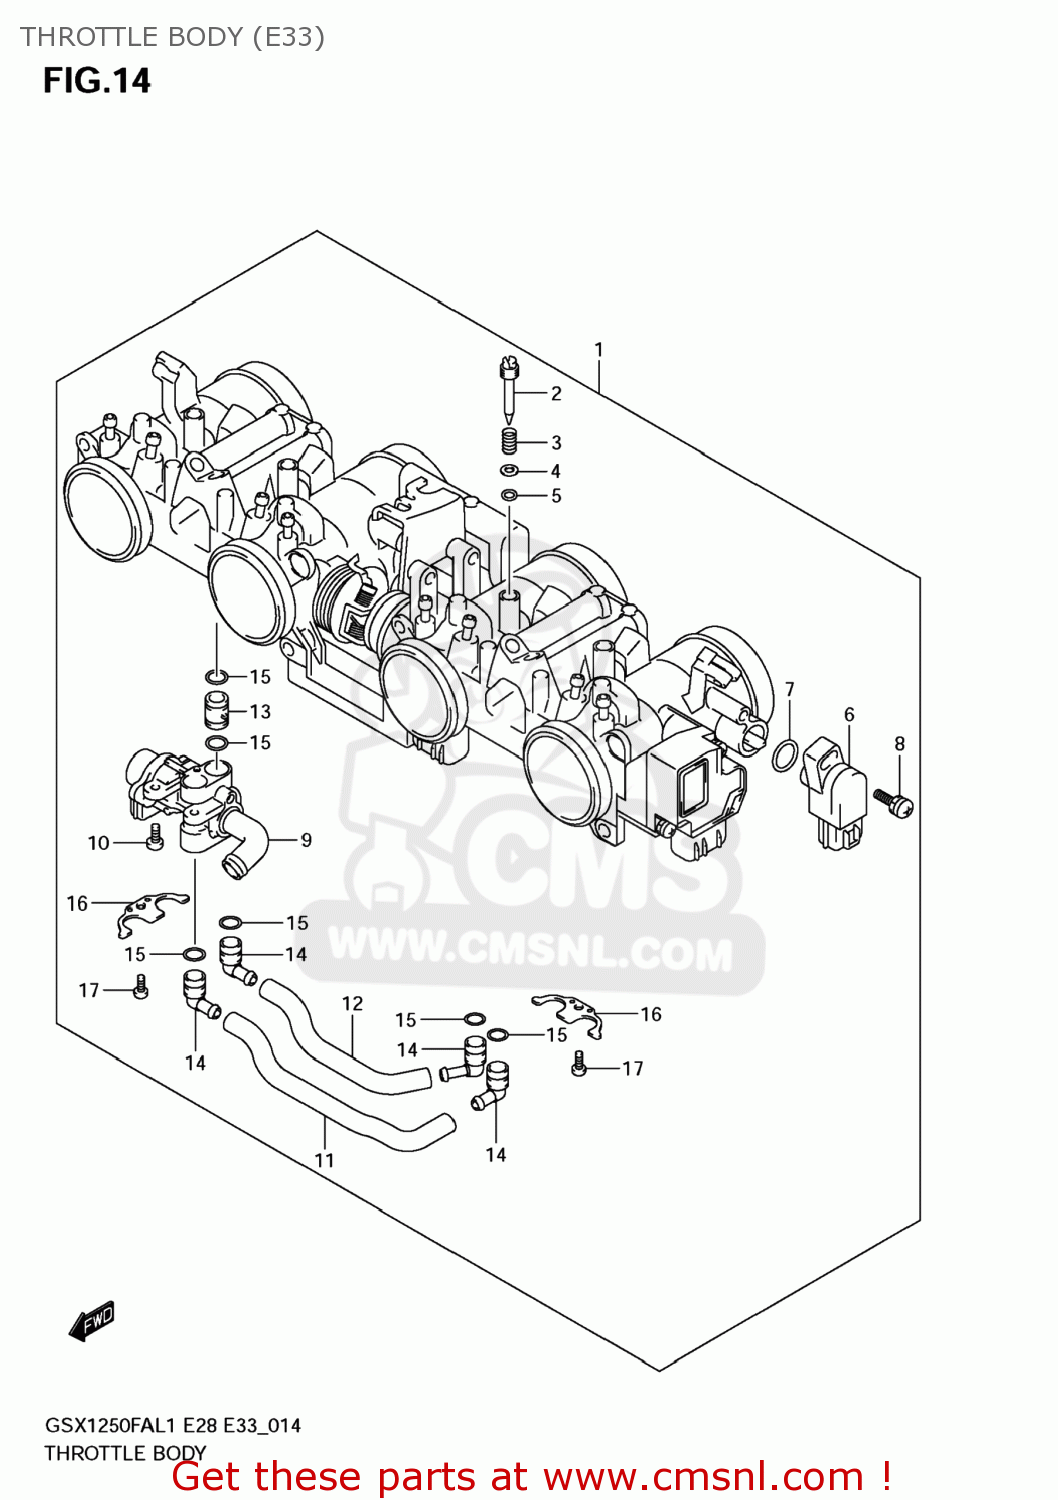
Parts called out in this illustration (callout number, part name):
1	BODY ASSY,THROTTLE
2	SCREW
3	SPRING,THROTTLE SCREW
4	WASHER
5	O RING,PILOT AIR SCREW
6	SENSOR
7	O RING
8	SCREW
9	ACTUATOR
10	SCREW
11	HOSE
12	HOSE
13	PIPE
14	NIPPLE
15	O RING
16	PLATE
17	SCREW
